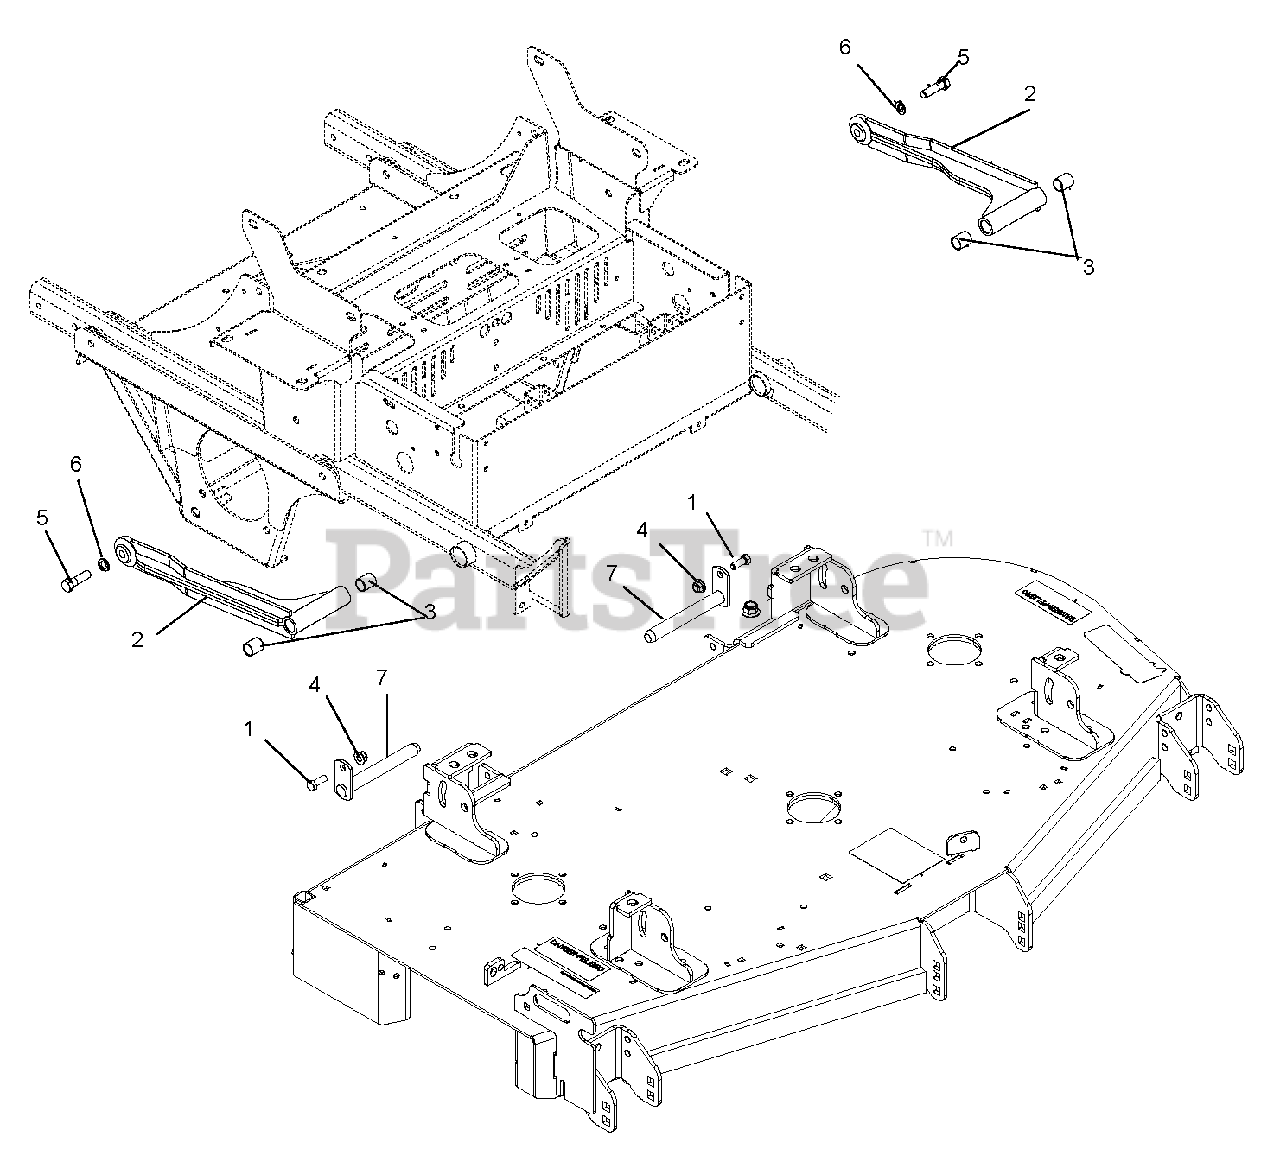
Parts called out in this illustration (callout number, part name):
1	Bolt, Hex .38-16 x 1.00 GR5 YWZC
2	Deck Stabilizer Arm - BLACK
3	Bearing, .75 x .875 x 1.00
4	Nut, Locking Nylon-Flange .38-16
5	Bolt, Hex .50-13 x 1.75 GR5 YWZC
6	Washer, Lock .50 x .125 REG YWZC
7	Weldment, Mower Mounting Pin
